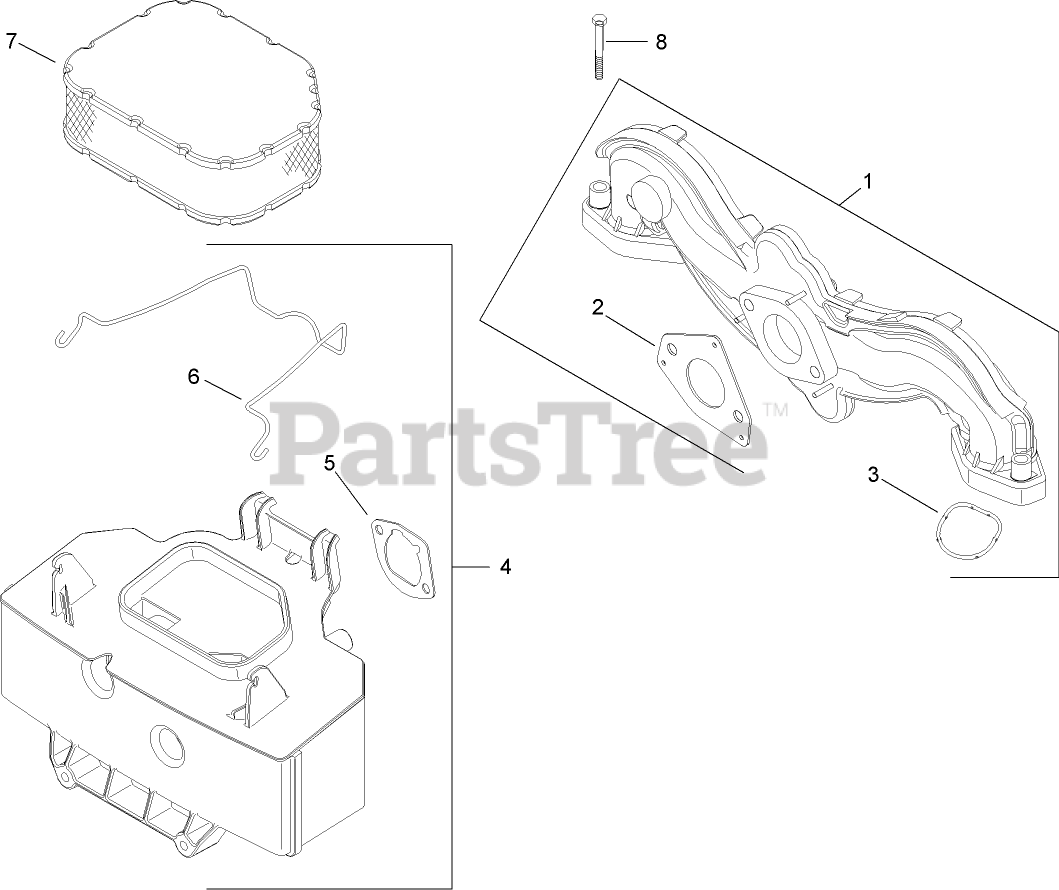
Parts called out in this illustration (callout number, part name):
1	Manifold-Intake (Includes?2-3)
2	Gasket-Carburetor
3	O Ring-Intake Port
4	Base-Air Cleaner (Includes?5-6)
5	Gasket-Air Cleaner Base
6	Latch-Air Cleaner Element
7	FILTER-AIR
8	Screw-Hex Flange (M6x1.0x40)
